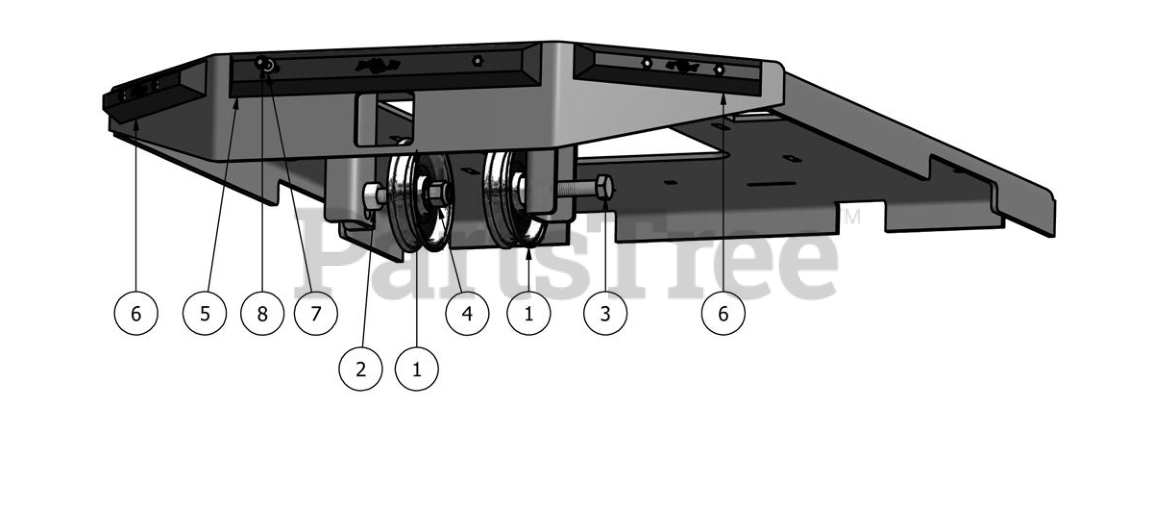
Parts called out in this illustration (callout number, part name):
1	5" V Idler Pulley
2	5/8" x 1/2" Collar Spacer
3	5/8" x 2 1/2" Bolt
4	5/8" Nylock Nut
5	14" Bumper
7	1/4" Flat Washer
8	1/4" x 1 1/2" Self Tapping Screw
